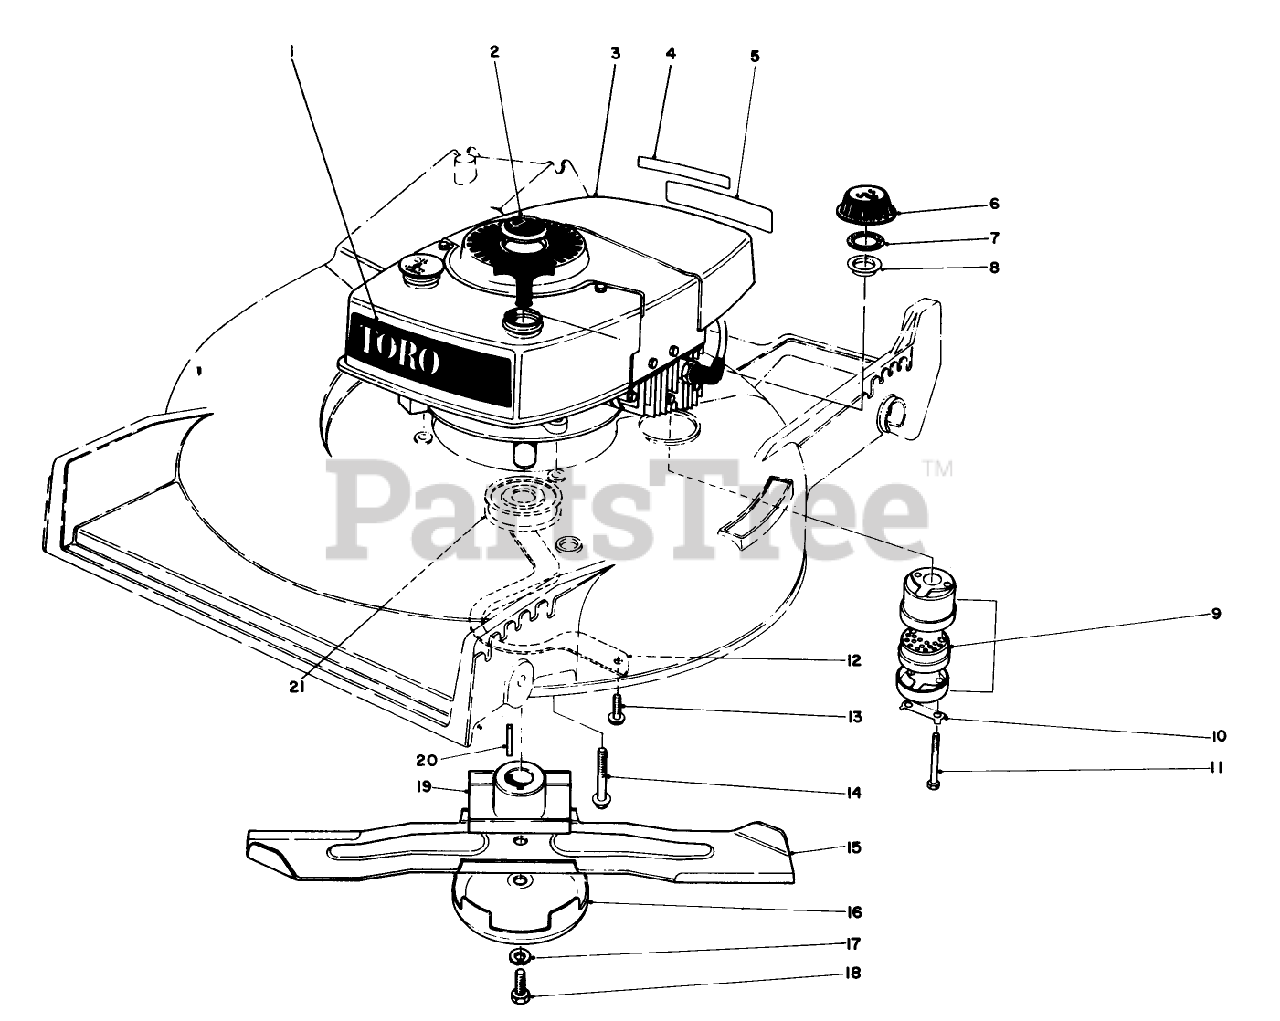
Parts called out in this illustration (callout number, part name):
1	Decal Toro
2	Plug Button
3	Engine
4	Decal-Primer Bulb
5	Decal Maintenance
6	Gas Cap (Incl. Ref. #7 & 8)
7	GASKET
8	GAS CAP BAFFLE
9	Muffler Assembly (Incl. Ref. #10 & 11)
10	CLIP - LOCKING
11	SCREW-HH
12	BELT GUIDE
13	Screw
14	SCREW-HWHTF
15	Blade
16	AntiScalp Cup
17	WASHER-LOCK
18	BLADE SCREW
19	BLADE RETAINER WA(BLACK)
20	KEY-SQUARE
21	DRIVER PULLEY
